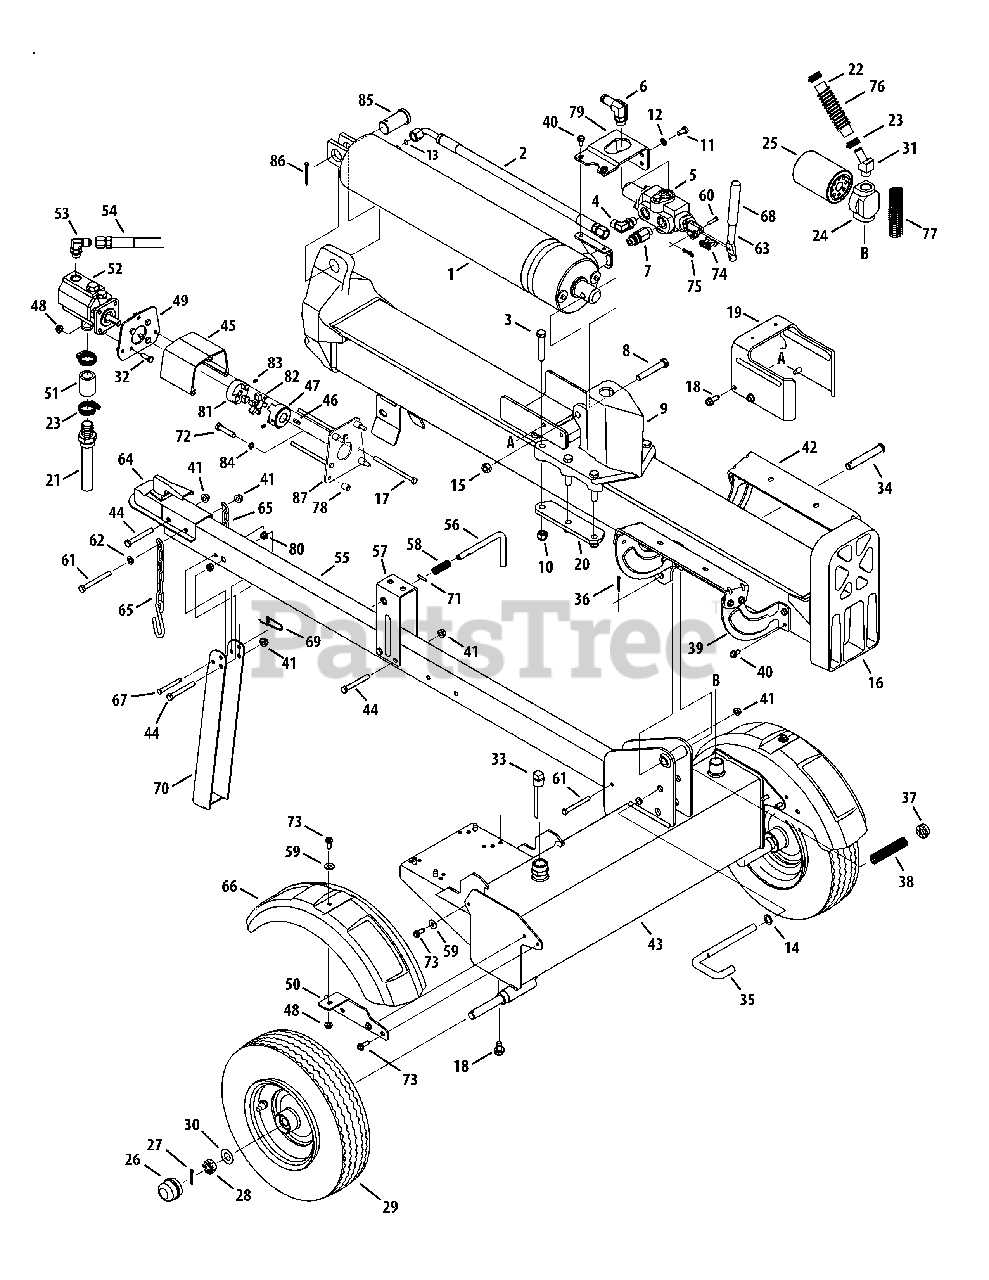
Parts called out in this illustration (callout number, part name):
2	Hydraulic Tube
3	Hex Cap Screw, 1/2-20 x 2.75
4	90 Degree Solid Adapter
5	Control Valve
6	Return Elbow
7	Nipple Pipe, 1/2-14
8	Hex Cap Screw, 1/2-13 x 3.25
9	Wedge Assembly
10	Hex Lock Nut, 1/2-20
11	Hex Cap Screw, 3/8-16 x .75
12	Lock Washer, 3/8
13	O-Ring, .489 ID x .070 Dia.
14	Flat Washer, .635 x.93 x.06
15	Hex Lock Nut, 1/2-13
16	Beam Assembly
17	Hex Screw, 5/16-18 x 4.75
18	Self Tapping Screw, 3/8-16 x 1.0
19	Dislodger Bracket
21	Inlet Filter
22	Return Hose, 3/4 x 44
23	Hose Clamp, 5/8
24	Filter Housing
25	Oil Filter
27	Cotter Pin
28	Slotted Nut, 3/4-16
29	Complete Wheel Assembly
29	Dust Seal
29	Roller Bearing
30	Flat Washer, .760 x 1.500
31	Hydraulic Fitting, 1 1/16 Orb x .75
32	Hex Screw, 5/16-18 x 1.00
33	Vented Dipstick
34	Clevis Pin
36	Cotter Pin
38	Compression Spring
39	Log Tray Bracket
40	Hex Washer Screw, 5/16-18 x .750
41	Flange Lock Nut, 3/8-16
43	Frame Assembly
44	Hex Bolt, 3/8-16 x 3
45	Coupling Shield
46	Square Key, 3/16 x .75
47	Coupling, .875
48	Flange Lock Nut, 5/16-18
49	Rear Coupling Support Bracket
50	Fender Mounting Bracket
53	Hydraulic Fitting, 7/8 Orb x .8125
54	High Pressure Hydraulic Hose
55	Tongue Assembly
56	Latch Rod
58	Compression Spring
59	Flat Washer
60	Clevis Pin
61	Hex Cap Screw, 3/8-16 x 3.50
62	Flat Washer, .375 x.738 x.063
63	Hydraulic Valve Control
64	Hitch Coupling Assembly
67	Clevis Pin
69	Spring Pin
71	Spiral Pin
72	Hex Cap Screw, 5/16-24 x .75
73	Self-Tapping Screw, 5/16-18 x 1.00
74	Valve Handle Link
75	Cotter Pin, Bow Tie
76	Hose Guard, 48"
77	Hose Guard, 44"
78	Spacer, .385 x .623 x .75 LG
79	Outer Valve Bracket
80	Plastic Bushing, .380 ID
81	Coupling, .500
82	Spider Bushing
83	Set Screws
84	Lock Washer, 5/16
85	Clevis Pin, 1.25 x 2.50
86	Cotter Pin, 3/16 x 2
87	Front Coupling Support Bracket
